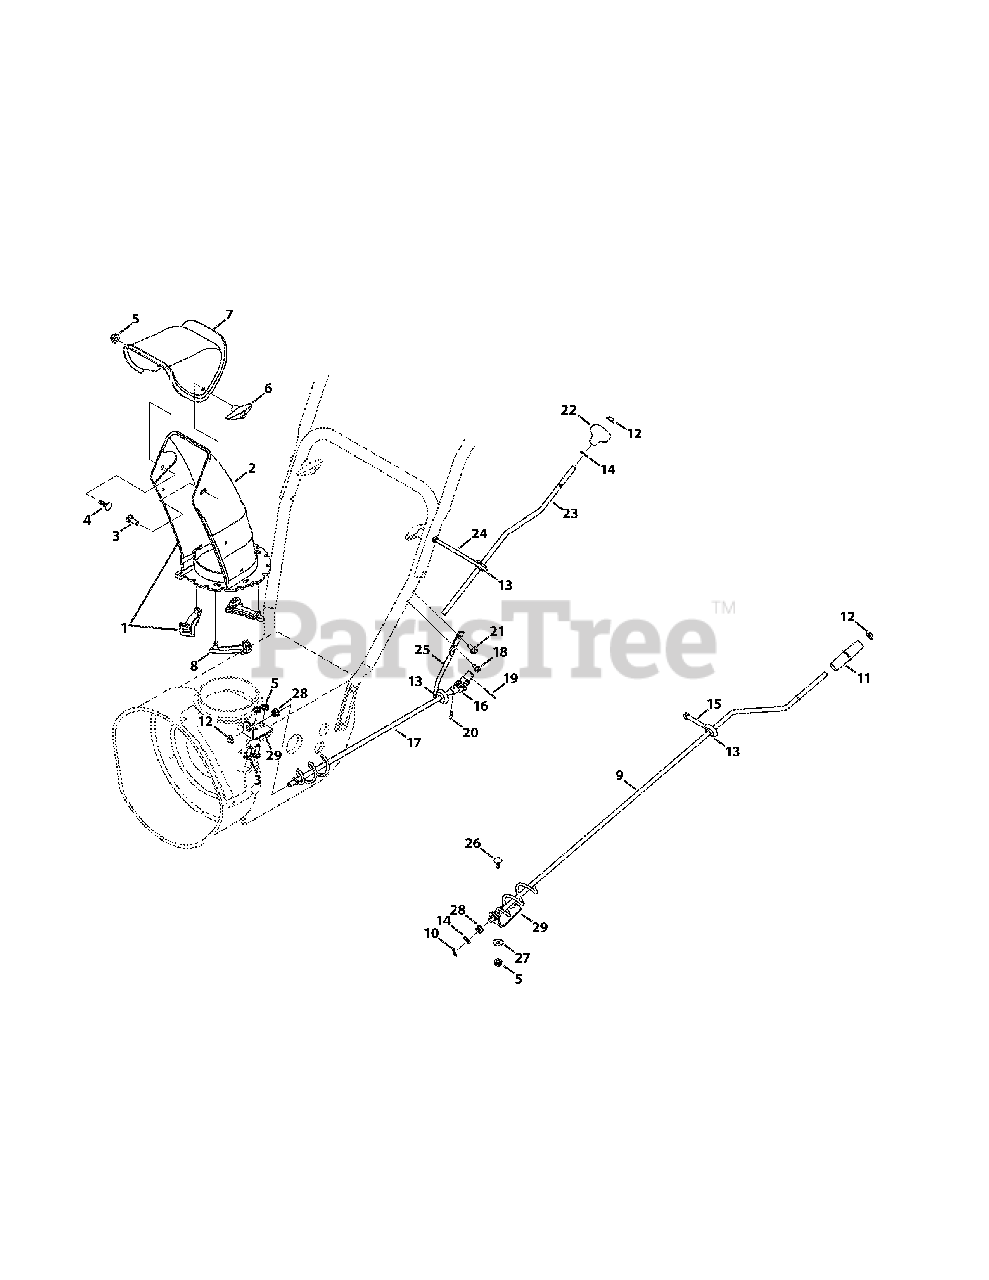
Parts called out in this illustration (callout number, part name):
1	Lower Chute Assembly
2	Lower Chute
3	Carriage Bolt, 5/16-18 x 1.00
4	Carriage Bolt, 5/16-18 x .750
5	Flange Lock Nut, 5/16-18
6	Wing Knob
7	Upper Chute
8	Flange Keeper
9	Chute Crank
10	Cotter Pin, .072 x 1.13
11	Crank Knob
12	Push Cap, 3/8
13	Rubber Grommet
14	Flat Washer, .375 x .738 x .063
15	Eye Bolt
16	Joint Assembly
17	Chute Crank
18	Taptite Screw, 1/4-20 x .500
19	Cotter Pin, .08 x 1.42
20	Pin, .156 x .875
21	Taptite Screw, 5/16-18 x 2.25
22	Shift Knob
24	Chute Rod Eye Bolt
25	Lower Chute Rod
26	Carriage Screw, 5/16-18 x 1.00
27	Flat Washer, .349 x .879 x .063
28	Plastic Bushing, .380 ID
29	Chute Crank Bracket
